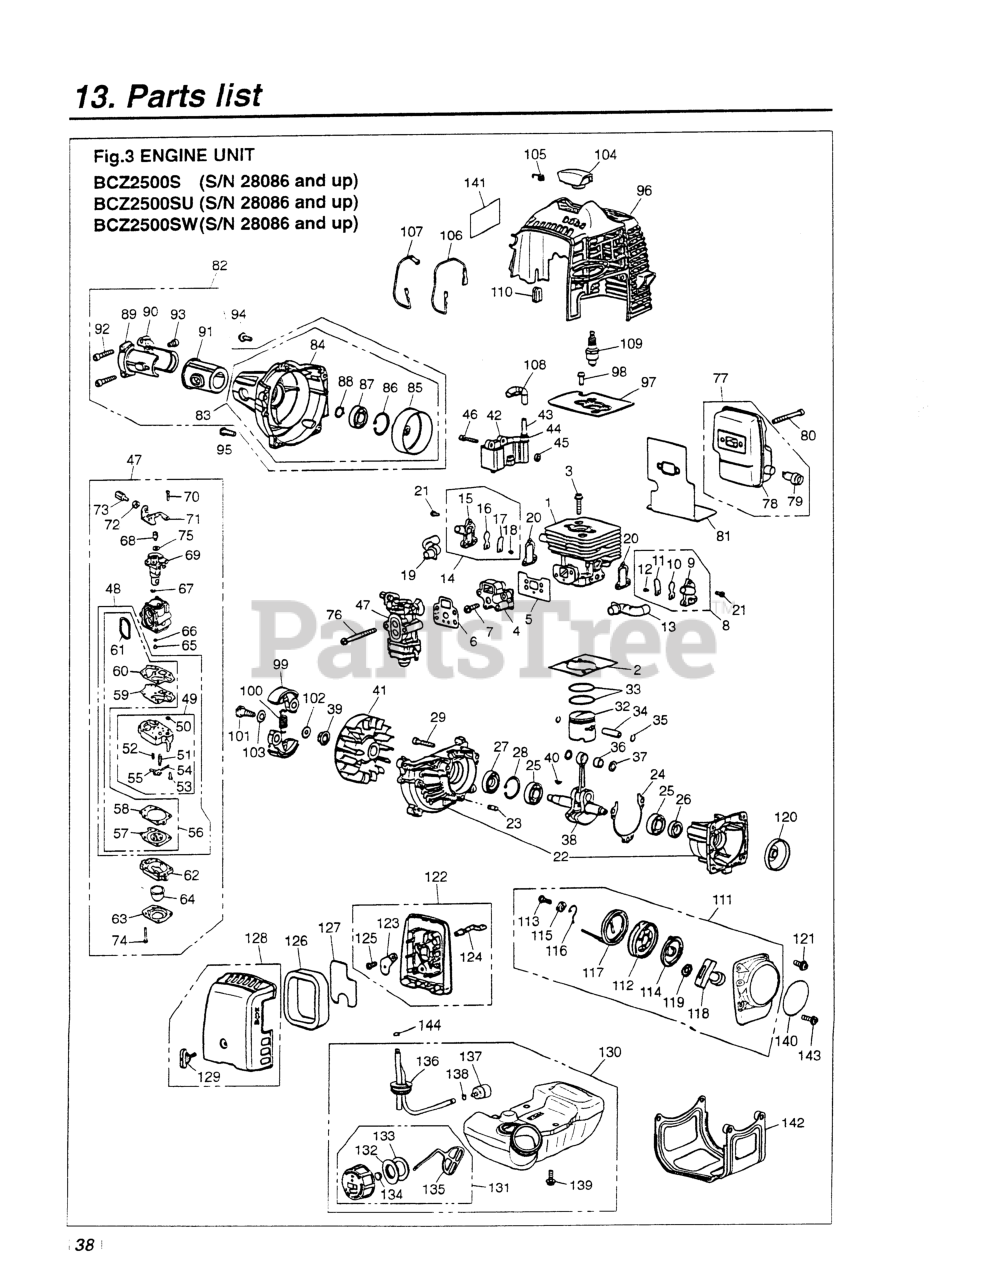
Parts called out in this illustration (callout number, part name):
1	CYLINDER (RPLS -12110)
2	GASKET, BASE
3	BOLT, M5 X 22
4	INSULATOR (RPLS. -13160/13161)
5	GASKET, INSULATOR
6	GASKET, CARBURETOR
7	SCREW, M5X20 (RPLS.1400-75510)
9	CASE VALVE
10	VALVE, REED
11	STOPPER
12	SCREW, M3 x 8
13	PIPE, AIR
16	VALVE, REED
17	STOPPER
18	SCREW, M3 x 8
19	PIPE, AIR (F)
20	GASKET, VALVE
21	SCREW
22	CRANKCASE-C
23	PIN
24	GASKET
25	BEARING
26	SEAL
27	SEAL, OIL (RPLS 1140-21220)
28	RING, SNAP, M28 x 1.2
29	BOLT, M5 X 30
32	PISTON
33	RING, PISTON
34	PIN, PISTON
35	RING, SNAP (RPLS 1101-41320)
36	BEARING (RPLS 1140-41330)
37	WASHER
38	CRANKSHAFT COMPLETE
40	KEY
41	ROTOR
42	COIL-A
43	CORD
44	CAP
45	SPACER (RPLS -71260)
46	BOLT, M4 x 22
49	PUMP BODY ASSEMBLY
50	SCREEN
51	VALVE, INLET
53	SCREW
54	PIN
55	LEVER
57	DIAPHRAGM
58	GASKET, DIAPHRAGM
59	DIAPHRAGM, PUMP
60	GASKET, PUMP
61	RING
62	BODY, PURGE
63	COVER, PUMP
64	PUMP, PRIMING
65	JET (REPLACES 4810-81250)
66	RING, O
67	RING
68	SWIVEL
69	VALVE ASSY
70	SCREW
72	NUT, CABLE ADJUSTER
73	SCREW, CABLE ADJUSTER
74	SCREW
75	WASHER
76	SCREW, M5 x 60
77	MUFFLER ASSEMBLY
78	MUFFLER (REPLACES -15110)
79	ARRESTER
80	BOLT, M5 x 50
82	COVER-A (USE -31002)
83	COVER-C (USE -31102)
84	COVER, FAN (USE -31111)
86	RING, SNAP, M28 x 1.2
88	RING, SNAP (RPLS 3130-13270)
89	BRACKET (A) (RPLS -31210)
90	BRACKET (B) (REPLACES -31220)
91	CUSHION
92	BOLT, M5 X 30
93	BOLT (USE 3310-31720)
94	SCREW
95	SCREW, M5X20 (RPLS.1400-75510)
96	COVER, ENGINE (RPLS -32110)
97	PLATE
98	SCREW, M5 X 10
99	SHOE
100	SPRING
101	BOLT
102	WASHER, FLAT (USE 182303)
103	WASHER (RPLS -51241)
105	SPRING
106	CORD (BLACK)
107	CORD, EARTH (RED)
110	GROMMET
111	RECOIL ASSEMBLY
112	REEL
113	SCREW
114	SPRING, SPIRAL
115	COLLAR
116	ARM
117	ROPE (REPLACES 4500-75160)
118	KNOB (RPLS -75420)
119	PLATE, STOPPER
120	PULLEY
121	SCREW
122	BODY ASSEMBLY
123	PLATE, CHOKE
124	LEVER, CHOKE
125	SCREW (REPLACES 50030272)
126	ELEMENT
127	SCREEN
128	COVER ASSEMBLY
129	KNOB (RPLS -82220)
131	CAP ASSY (RPLS -85201)
132	HOLDER (REPLACES -85230)
133	PACKING
134	FILTER
135	STOPPER
136	PIPE COMPLETE
137	FILTER (RPLS 1850-85300)
138	CLIP (REPLACES 2841-31280)
139	SCREW
140	LABEL, RECOIL
141	LABEL, COVER (RPLS -31130)
142	GUARD (RPLS 4810-31911)
143	SCREW, M5 x 25
144	CLIP
